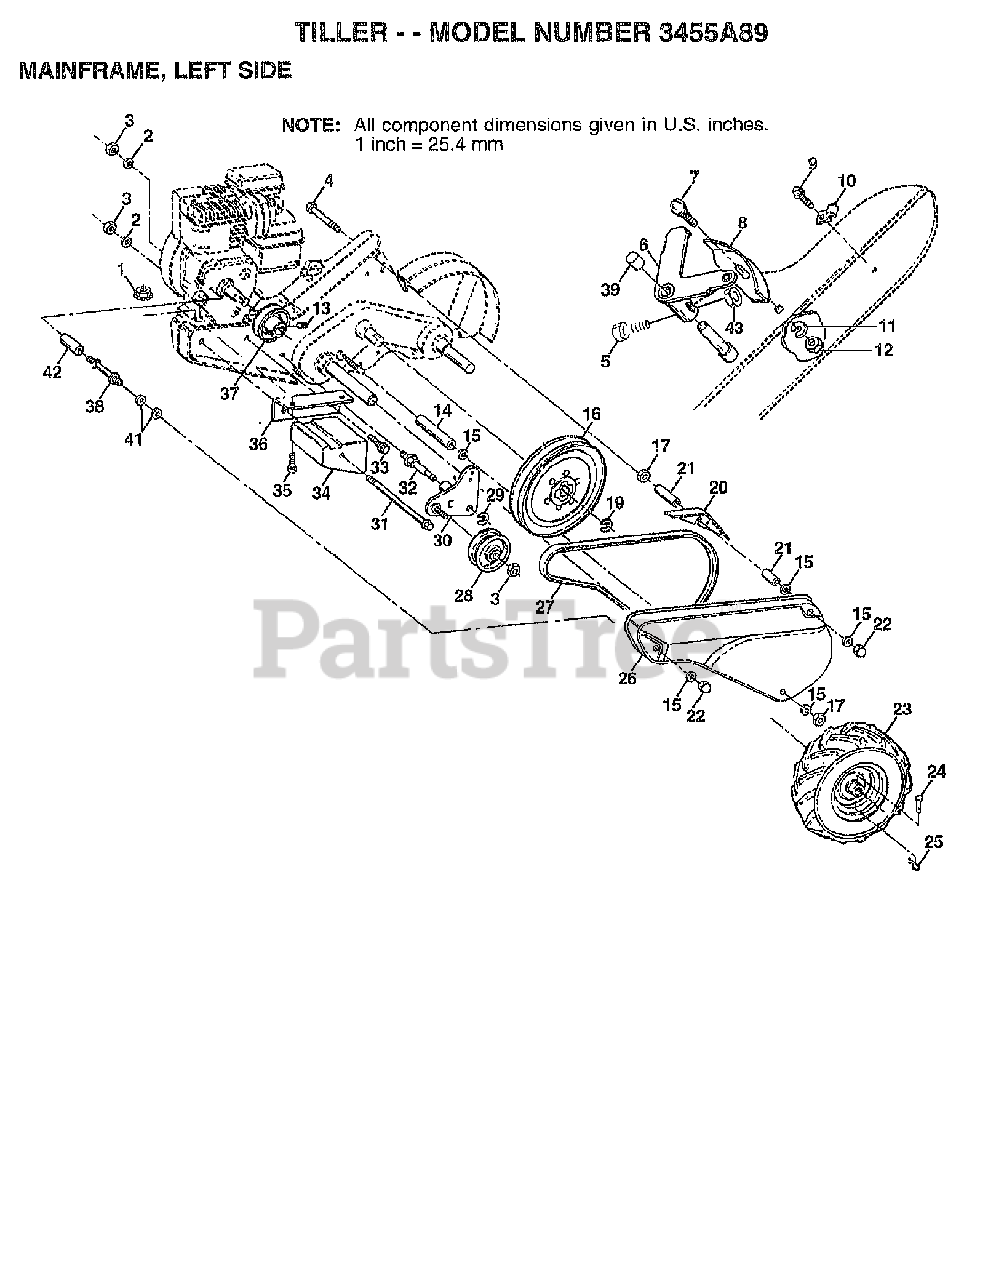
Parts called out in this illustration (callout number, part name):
2	WASHER, LOCK 3/8
3	NUT.HEX.3/8-16UNC
5	SCREW, SHIFT LEVER
6	LEVER ASM CRT
8	PANEL.INDICATOR.SHIFT.BLACK
10	CONDUIT CLIP T
11	LOCKWASHER
12	NUT
13	SET SCREW
14	SPACER
15	WASHER
16	SHEAVE, TRANSMISSION
19	RETAINING RING LT
20	GUARD CRT
21	SPACER, SPLIT
23	TIRE.16X4-8.CHEVRON.TILLER
23	RIM
24	RIVET CRT
26	BELT GUARD
27	V-BELT
28	PULLEY-IDLER TI
29	KLIP RING
30	BRACKET.ASM.IDLER.BLACK
31	BOLT.FIN.HEX.3/8-16UNC
32	SHIFT ARM CRT
33	BOLT
34	COUNTERWEIGHT.LH.CRT
35	BOLT
36	BRACKET LH CRT
37	ENGINE PULLEY
38	BELT GUARD STUD
39	CAP.PLUNGER.BLACK
42	SPACER
